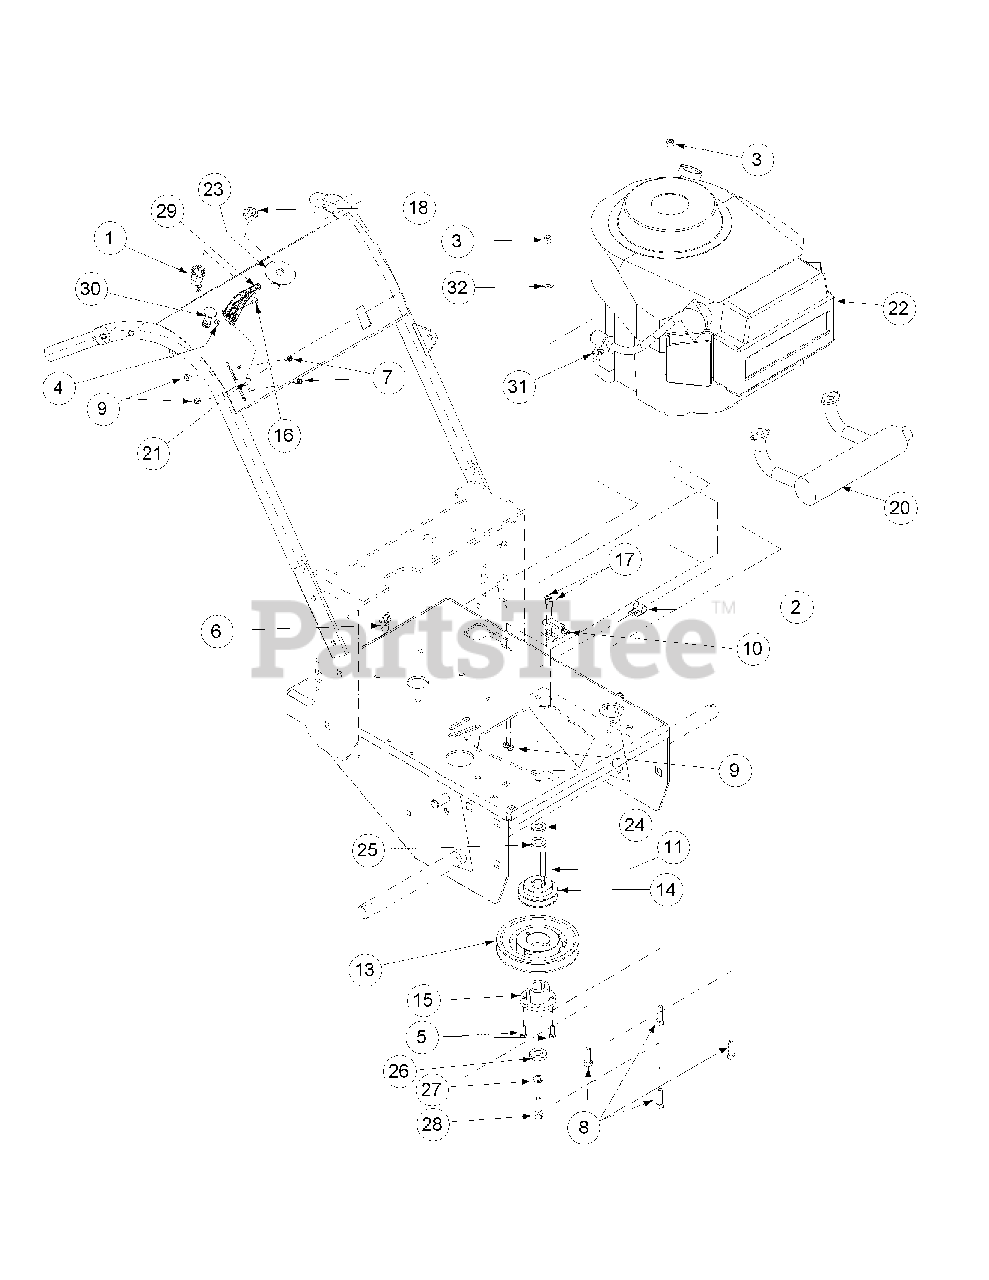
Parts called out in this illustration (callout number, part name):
1	Ignition ON/OFF Switch
2	Support Clamp
3	Nut, 5/16-18 Nylock
4	Nut, 8-32, w/ star washer
5	Hex Cap Screw, 1/4-20, .75
6	Support Clamp
7	Screw, Hex Washer, 10-32 x 1/2
8	Cap Screw, 5/16-18 x 2
9	Lock Nut, Nylon Insert, 10-32
10	Delta Switch
11	Key Stock, 1/4 x 1/4 x 2-3/4
13	Deck Pulley
14	Traction Drive Pulley
15	Bushing Type D
16	Machine Screw, 8-32
17	Machine Screw, 10-32 x 5/8
18	Nut, w/Cap, 5/8-32, Ignition
21	Throttle Control, w/Detent, 47.25
22	Engine, 15HP Kawasaki Kai
23	Decal, Pull Start Overlay
24	Engine Pulley Spacer, 12.5 Vanguard
25	Flat Washer
26	Clutch Washer
27	Lock Washer, 7/16
28	Capscrew, M10 x 1.5
29	Throttle Control Knob
30	Choke Cable
31	Hex Nut, 5/16-18
32	Flat Washer, 5/16
